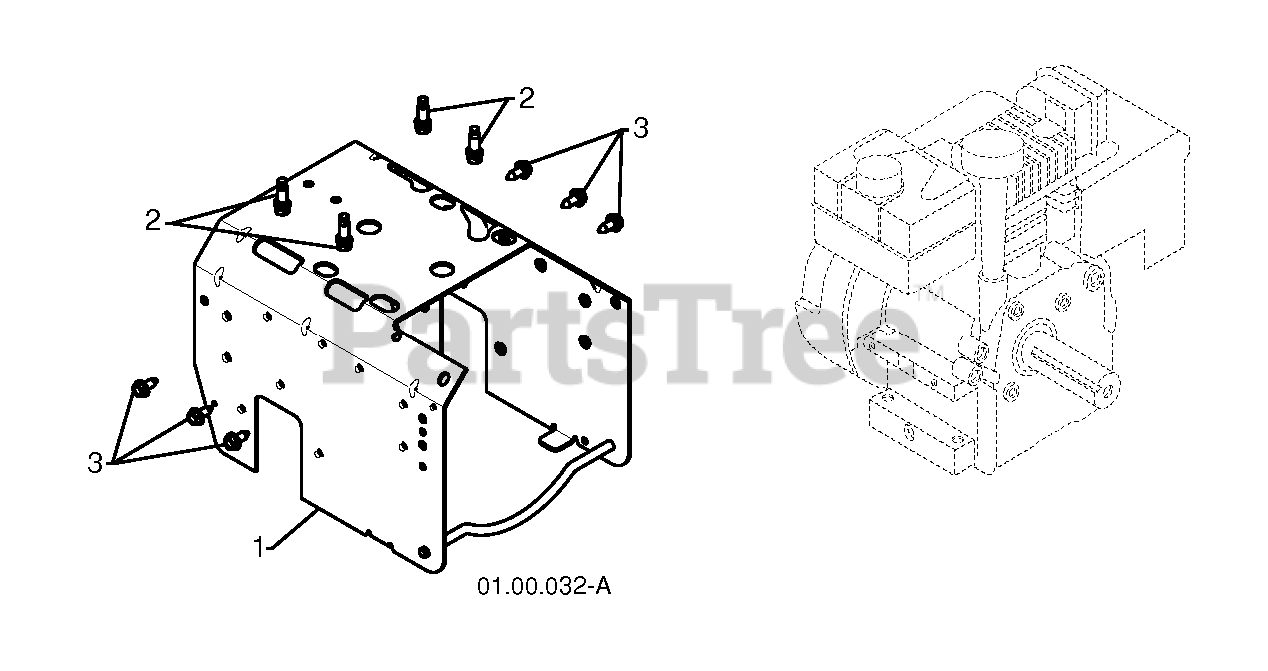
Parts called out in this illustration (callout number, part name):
1	FRAME.WELD.HYDRO.ORANGE
2	BOLT 3/8-16X1-1/8
3	BOLT.HEX.HD.WASHER.5/16-18X.75
